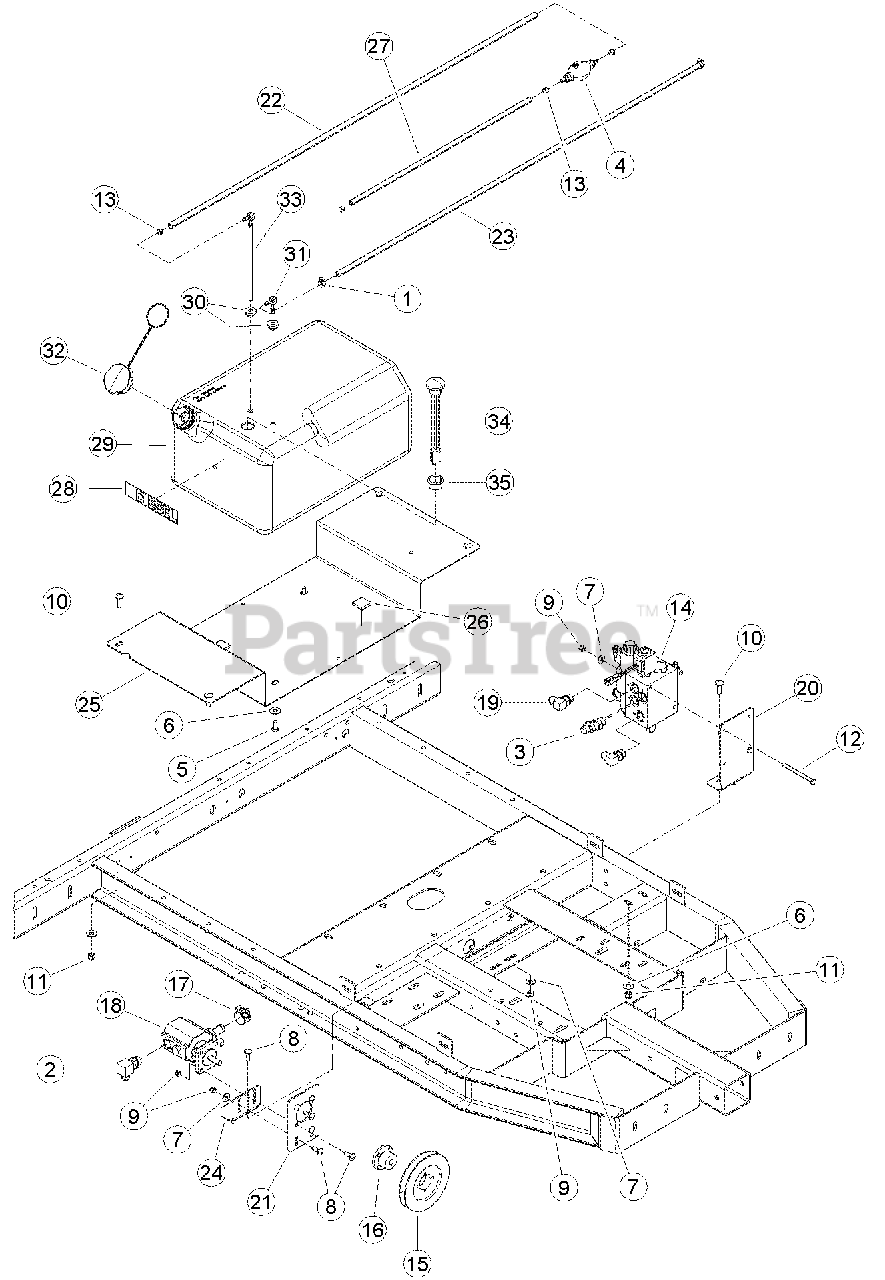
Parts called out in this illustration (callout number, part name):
1	CLAMP, HOSE 5/16 X 5/8 DIA MAX
2	ADAPTER, -10 MORING / -8 MJIC 90 DEG.
3	ADAPTER, -8 MORING / -8 MJIC
4	BULB, PRIMER
5	BOLT, 3/8 X 3/4 HEX HD GR5 ZP
6	WASHER, 3/8 FLAT ZP
7	WASHER, 5/16 FLAT ZP
8	BOLT, 5/16 X 1 CRG GR5 ZP
9	NUT, 5/16 NE NYLOCK ZP
10	BOLT, 3/8 X 1-1/4 CRG GR5 NC ZP
11	NUT, 3/8 NE NYLOCK ZP
12	BOLT, 5/16 X 4 HEX HD GR5 ZP
13	CLAMP, 15/32 SPRING
14	ASSEMBLY, CHIPPER VALVE
15	SHEAVE, QT 1B5.6
16	BUSHING, QT 1/2
17	CLAMP, 1-5/32 TO 7/32 OD RANGE T-BOLT
18	PUMP, 2 STAGE CW HI/LO 0.605 DISP.
19	ADAPTER, -8 MORING / -8 MJIC 90 DEG.
20	PLATE, VALVE MOUNTING
21	MOUNT, PUMP
22	HOSE, 63" FUEL LINE
23	HOSE, 63" RETURN LINE
24	MOUNT, PUMP
25	BASE, 9.25 GAL NYLON TANK
26	PAD, FOAM FUEL TANK DAMPER
27	HOSE, 38" FUEL
28	DECAL, DIESEL FUEL
29	TANK, 9.25 GAL ROTOMOLDED FUEL
30	GROMMET, TANK FITTING
31	FITTING, TANK VENT
32	CAP, FUEL TANK VENTED
33	FITTING, TANK FUEL PICK-UP TUBE
34	GAUGE, FUEL LEVEL KELCH 100
35	GROMMET, KELCH 100 GAUGE
